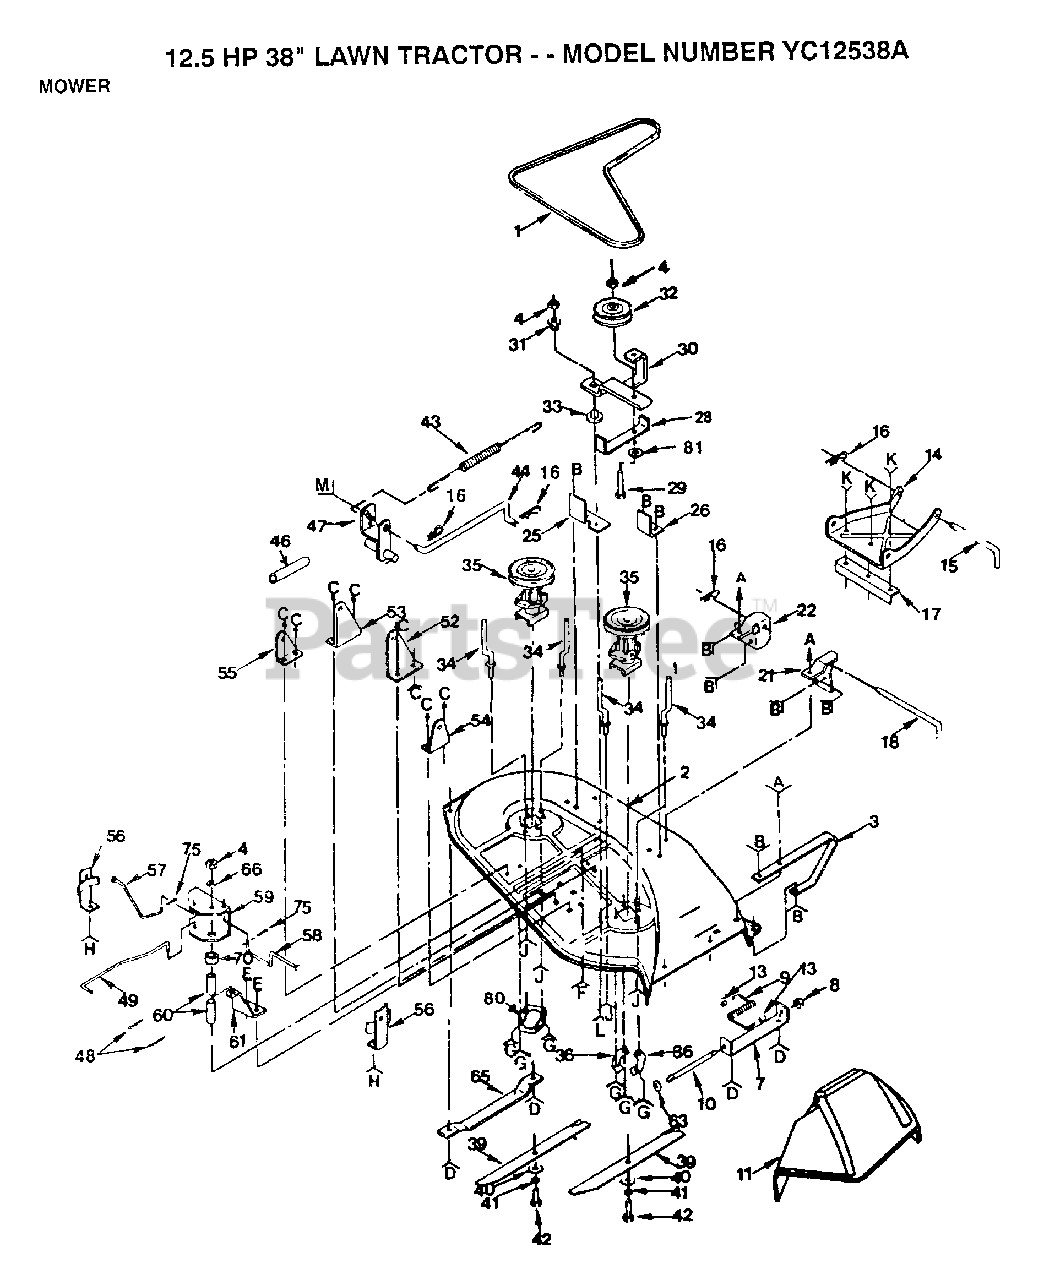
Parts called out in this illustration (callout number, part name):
1	BELT-V.79.1.MWR
8	NUT PUSH M
10	ROD-HINGE T
11	DEFLECTOR-SHLD T
13	CAP-SLEEVE LT
14	LINK.PARALLEL
15	"ROD, FRT. PARAL T"
16	SPRING.RETAINER
17	LINK STOP
18	HINGE PIN T
21	BRACKET RH LT
22	BRACKET LH T
25	SUPPORT ARM T
26	STOP T
31	SPACER RETAINER
33	"WASHER, WEAR LT"
34	BELT KEEPER LT
36	SUPPORT PLATE LT
39	"BLADE.38"" HI-LI"
40	WASHER
42	BOLT.3/8-24X1-1/2
46	SPACER T
49	ROD BRAKE LT
54	"BRKT,SUSP RH T"
55	"BRKT,SUSP REAR LH"
56	BRAKE LT
57	"ROD, BRAKE LH LT"
58	ROD BRAKE LT
59	"BRK,BRAKE,PVT LT"
60	SPACER BRAKE LTV
63	WASHER
65	RUNNER-LH M
66	WASHER
80	SUPPORT T
81	WASHER
